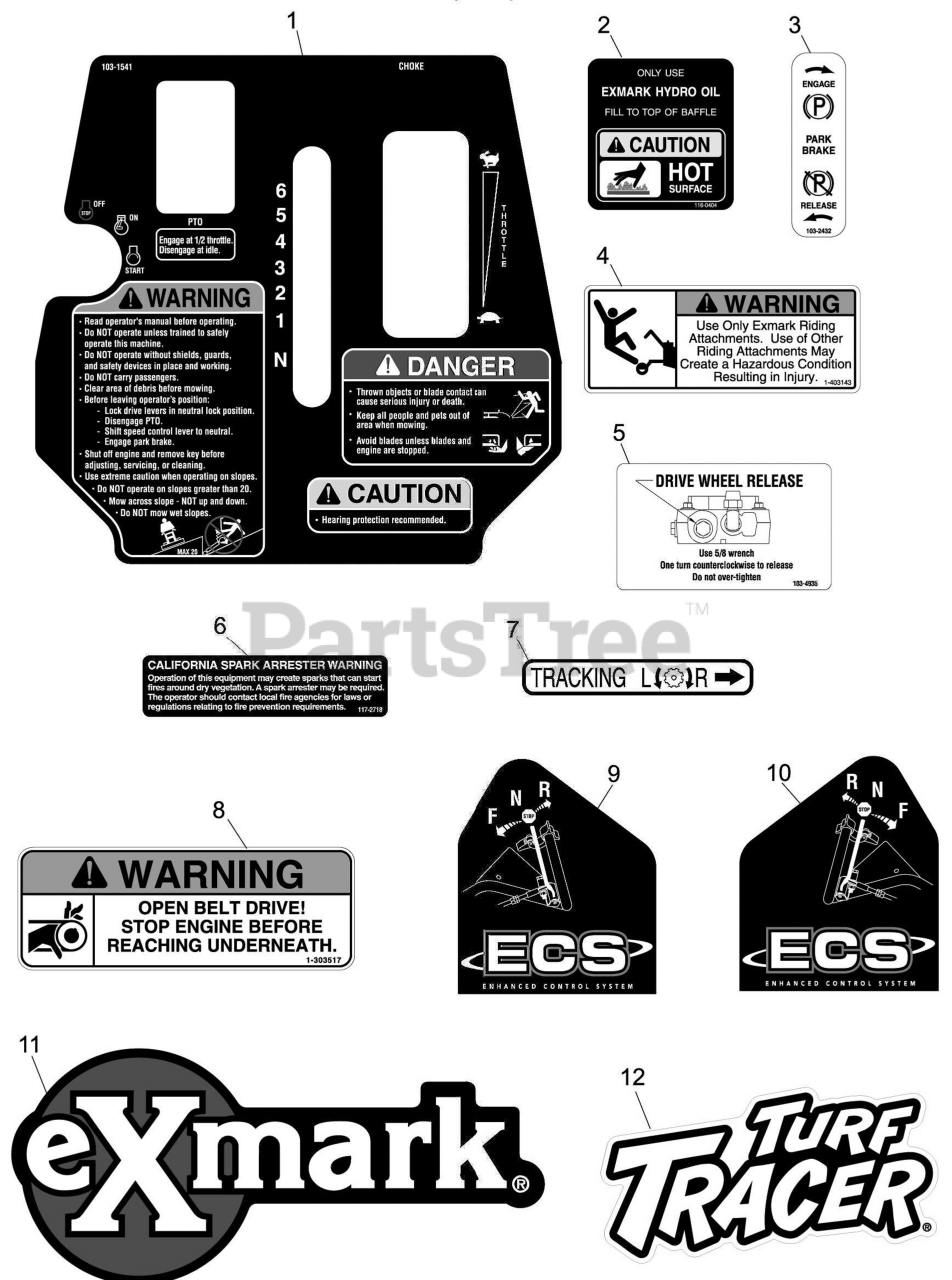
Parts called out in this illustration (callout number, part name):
1	DECAL,TTH ECS CONSOLE
2	DECAL-HYDRAULIC TANK
3	DECAL,SULKY WARNING
4	DECAL,PARKING BRAKE
5	DECAL,DRIVE RELEASE
6	DECAL-ARRESTER, SPARK
7	DECAL,TRACKING ADJUST
8	DECAL,BELT DRIVE
9	DECAL,LH ECS INSTRUCTION
10	DECAL,RH ECS INSTRUCTION
11	DECAL,EXMARK LOGO
12	DECAL,TTH MODEL
